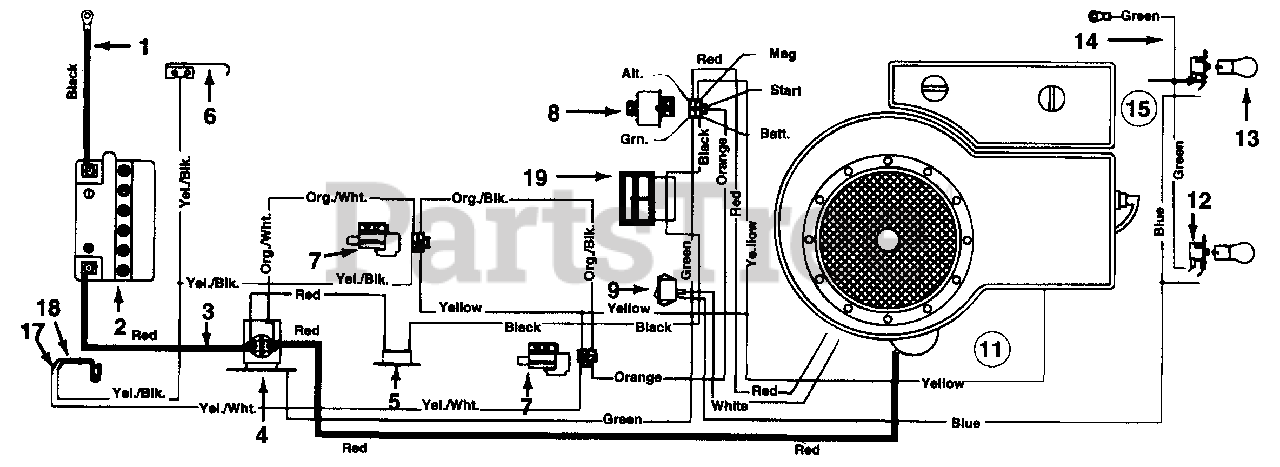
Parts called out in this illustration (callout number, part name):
1	Ground Wire
2	Battery
3	Electric Wire - 14.0" Lg.
4	Solenoid
5	Circuit Breaker
6	Spring Switch (Reverse)
7	Safety Switch
8	Ignition Switch
9	Light Switch
11	Harness w/Amp & Light Switch
12	Socket
13	Bulb
15	Headlight Harness w/Amp & Light Switch
17	Safety Switch (Outer)
18	Safety Switch (Inner)
19	Ammeter
